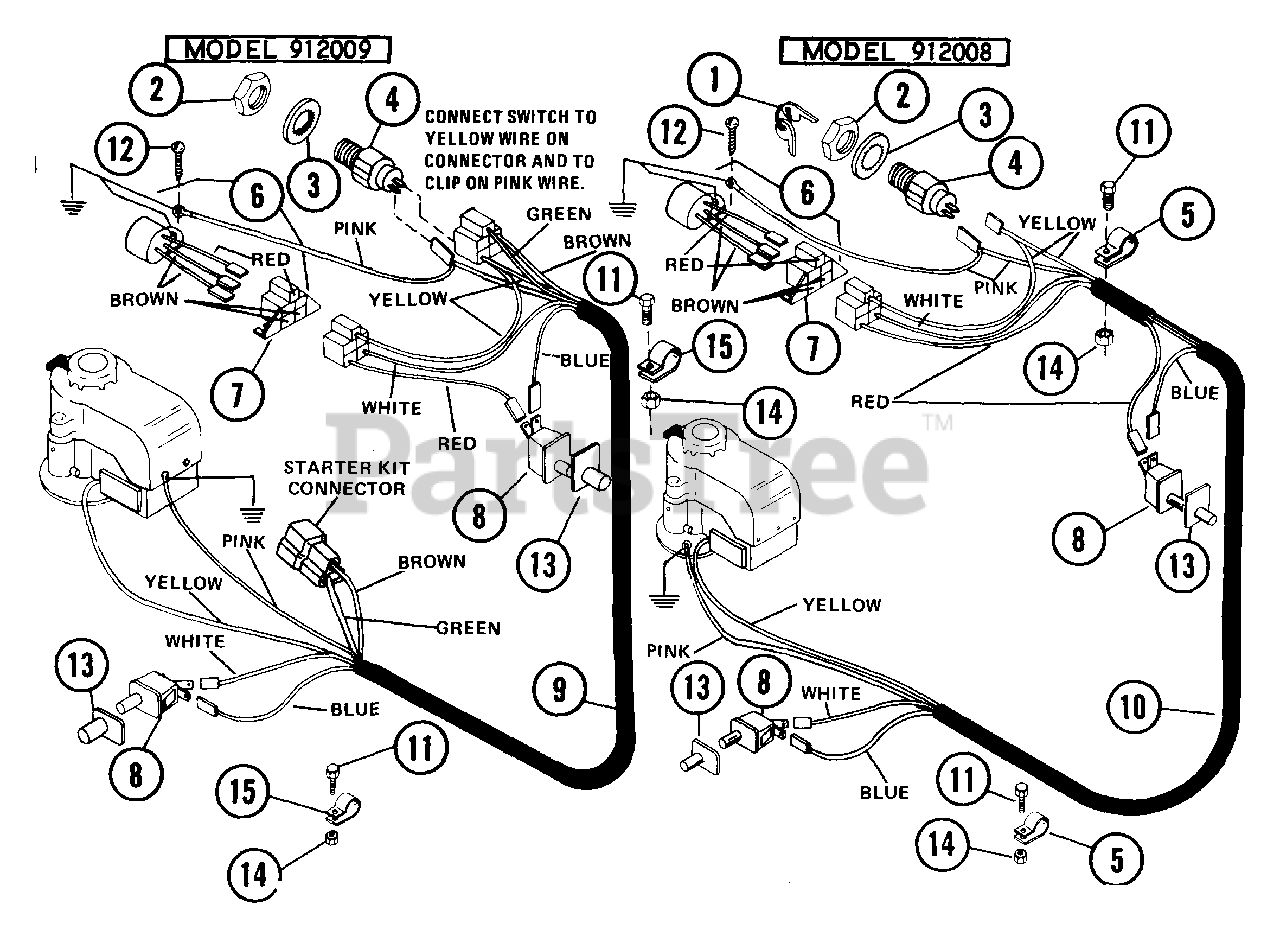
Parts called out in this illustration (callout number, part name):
1	KEYS
2	NUT .625-32 ALUM
3	WSHR-LK-INT .625X.045 PL
4	KEY SWITCH
5	CLIP
6	MODULE T KIT
7	CONNECTOR
9	WIRING HARNESS
10	WIRING HARNESS
11	BLT-HEX .25-20X.50 PL GR2
12	SCR-TAP 10-24X.375 HWH PL TR
13	SWITCH BOOT
14	NUT-LK-CTR .250-20 PL
15	CLIP
